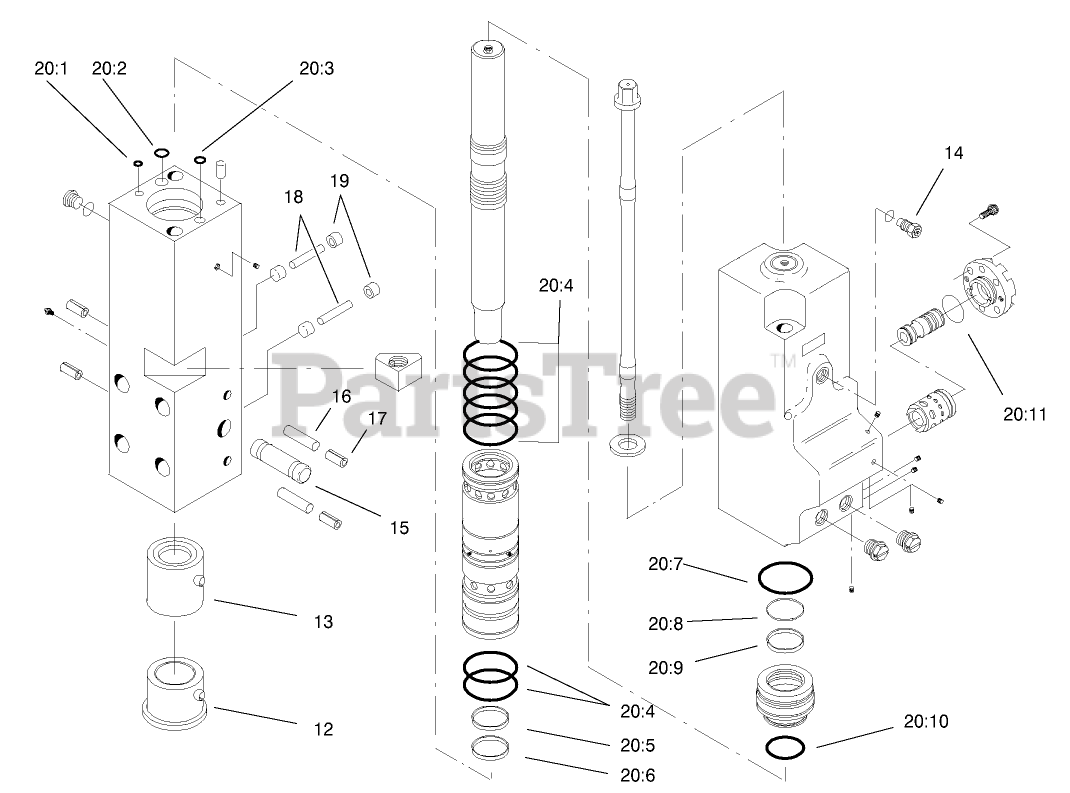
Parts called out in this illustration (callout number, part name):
12	LOWER BUSHING
13	UPPER BUSHING
14	CHARGE VALVE
15	TOOL RETAINER
16	DOWEL PIN
17	SPIRAL PIN
18	PIN RETAINER
19	RETAINER SPRING
20:6	Wiper-Rod
20:8	Ring-Quad, Modified
